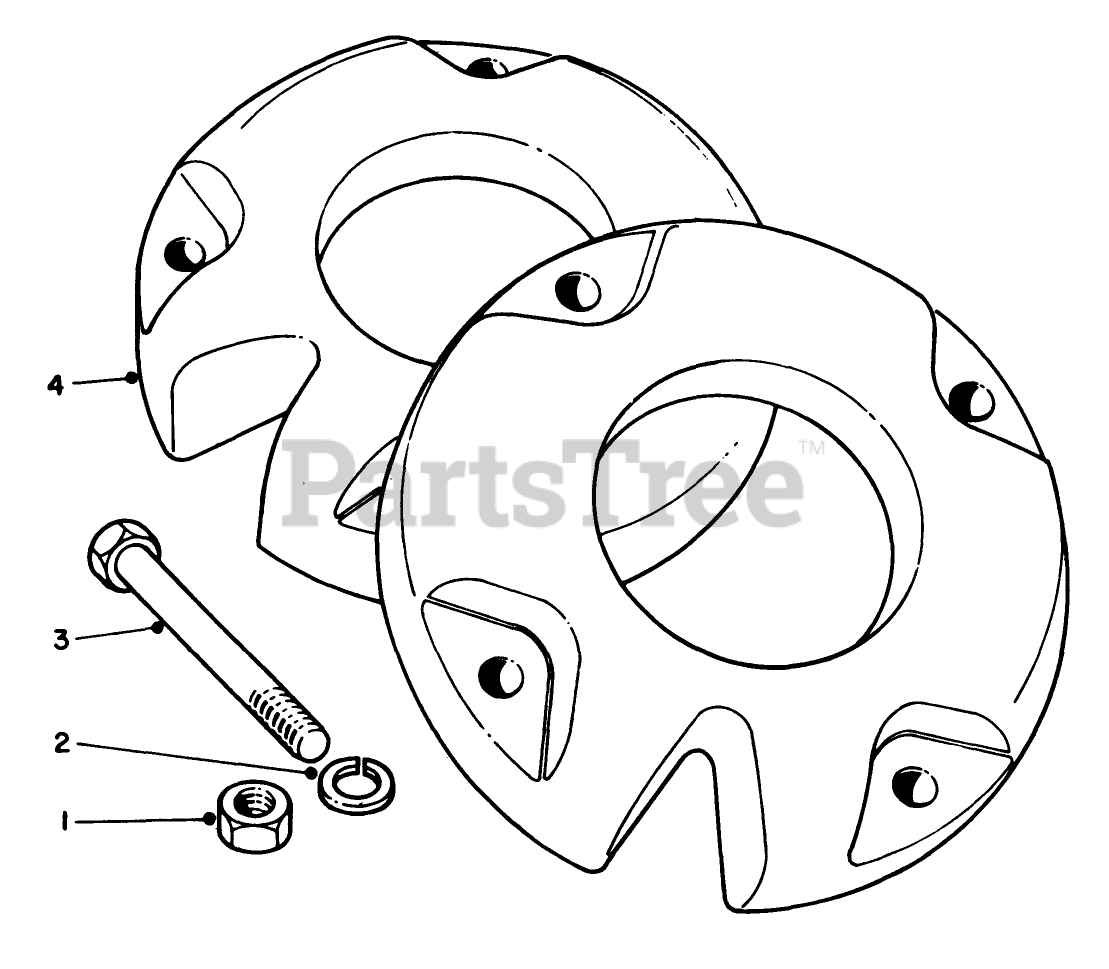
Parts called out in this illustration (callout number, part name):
1	NUT-JAM
2	WASHER-LOCK
3	SCREW-HH
4	Weight-Wheel
